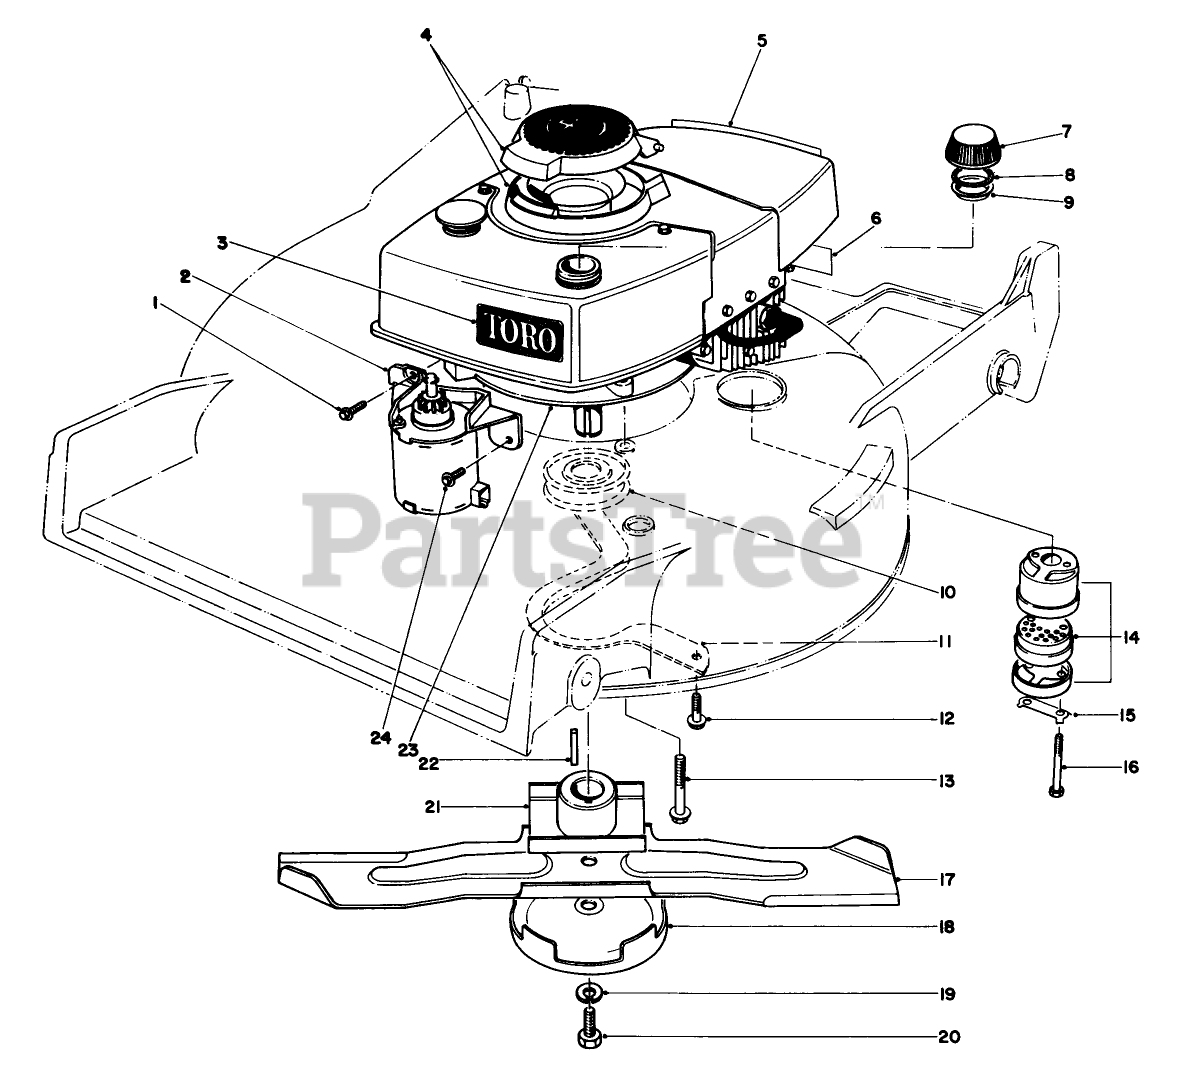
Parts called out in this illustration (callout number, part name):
1	Screw
2	Starter Motor
3	Decal Tow
4	COVER ASM
5	Decal Maintenance
6	Decal-Primer Bulb
7	Gas Cap (Incl. Ref. #8 & 9)
8	GASKET
9	GAS CAP BAFFLE
10	Engine Pulley
11	BELT GUIDE
12	Screw
13	SCREW-HWHTF
14	Muffler Assembly (Incl. Ref. #15 & 16)
15	CLIP - LOCKING
16	SCREW-HH
17	Blade 21"
18	AntiScalp Cup
19	WASHER-LOCK
20	Blade Screw
21	BLADE RETAINER WA(BLACK)
22	KEY-SQUARE
23	Engine
24	SCREW
